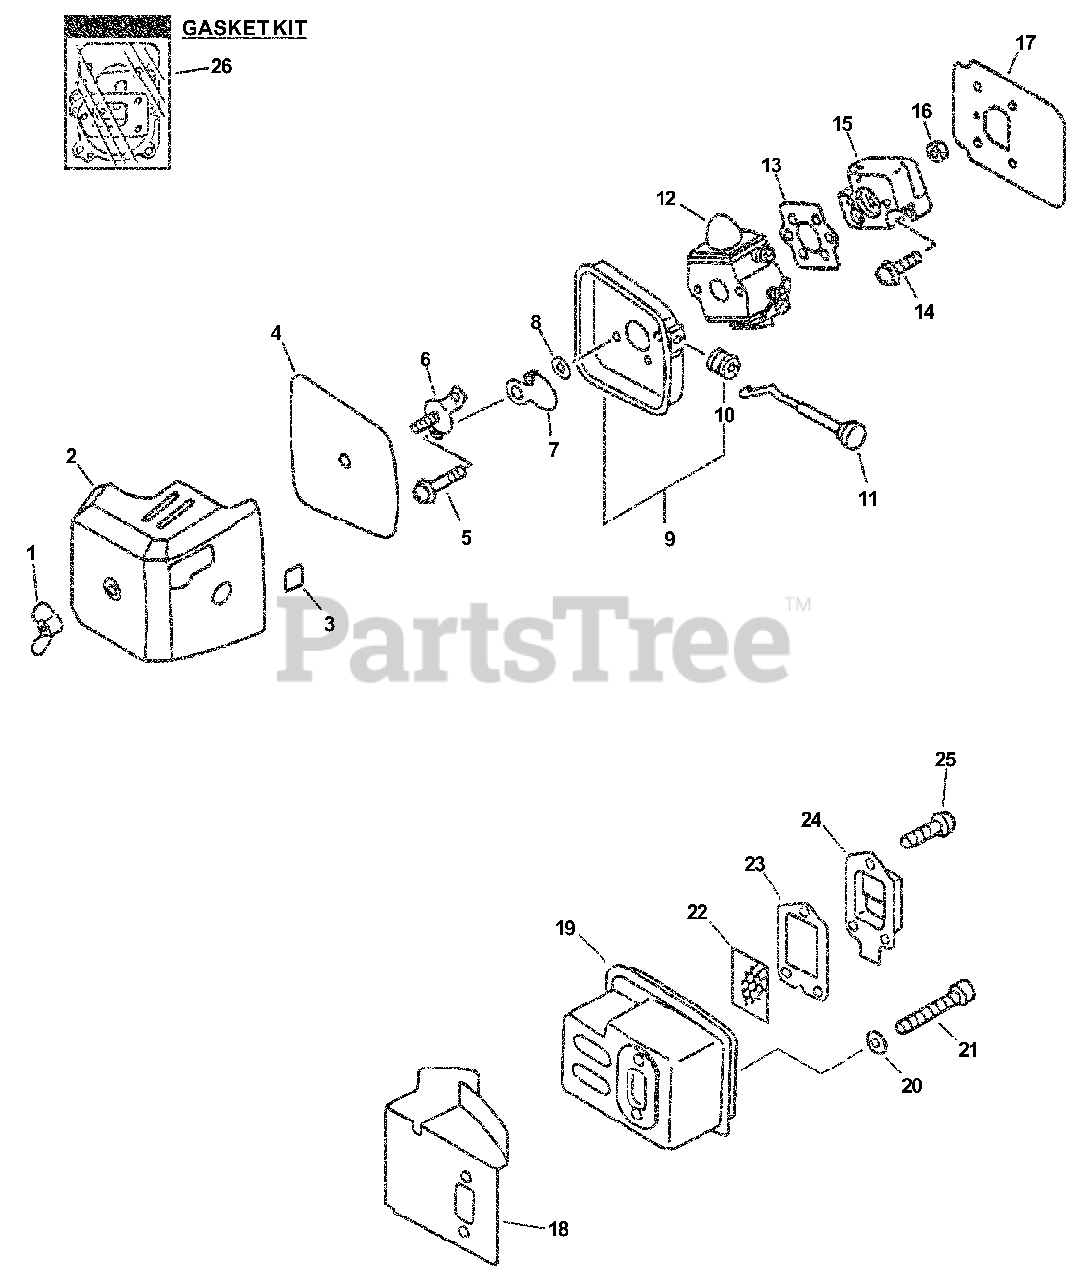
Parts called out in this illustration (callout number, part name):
1	WINGNUT - 6
2	COVER, AIR FILTER
3	LABEL - CHOKE
4	FILTER, AIR
5	SCREW - 5X57
6	PLATE, PREVENT
7	SHUTTER, CHOKE
8	WASHER - 5
9	CASE, AIR FILTER
11	ROD, CHOKE
12	CARBURETOR C1U-K54A
13	GASKET, INTAKE
14	SCREW - 5X20
15	INSULATOR, INTAKE
17	SHIELD, INTAKE
18	SHIELD, EXHAUST
20	WASHER - 5
21	SCREW - 5X50
22	SCREEN, SPARK ARRESTOR
23	GASKET, EXHAUST
24	GUIDE, EXHAUST
25	SCREW - 4X10
26	GASKET KIT
